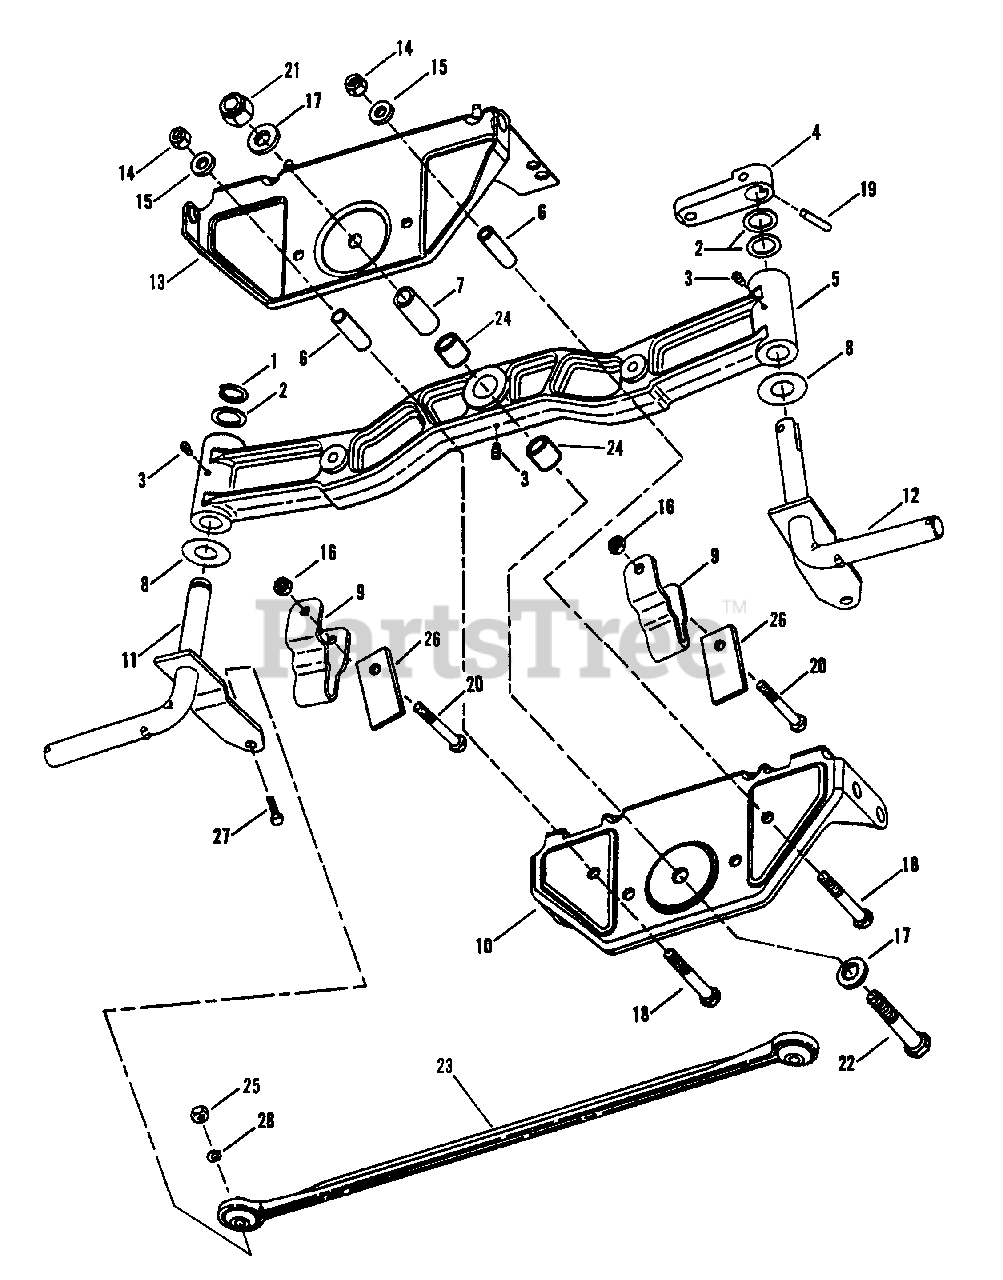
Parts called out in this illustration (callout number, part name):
1	RING, 5/8 External Retaining
2	WASHER, 49/64 x 1-1/8 x 1/16" Flat
3	FITTING, 3/16 Lube
4	ARM, Steering
5	AXLE, Cast
6	SPACER, 25/64 x 1/2 x 1-13/16"
7	SPACER, Center
8	WASHER, Thrust
9	BRACKET, Deck Hanger
10	BRACKET, Cast Axle (Rear)
11	WELDMENT, Right Hand Spindle Wheel (Long)
12	WELDMENT, Left Hand Spindle Wheel (Long)
13	ASSEMBLY, Cast Axle Front Bracket
14	NUT, 3/8-16 Hex Nyloc
15	WASHER, 3/8 x 5/64" Flat
16	NUT, 5/16-18 Hex Center Lock
17	WASHER, 1/2 x 3/32" Flat
18	SCREW, 3/8-16 x 2-3/4" Hex Head Cap, Grade 2
19	PIN, 1/4 x 1-1/4" Roll
20	SCREW, 5/16-18 x 2-3/4" Hex Head Cap, Grade 5
21	NUT, 1/2-13 Hex Nyloc
22	SCREW, 1/2-13 x 3" Hex Head Cap Grade 5
23	TIE ROD, Reduced Radius
24	BEARING, Sleeve
25	NUT, 3/8-16 Hex, Grade 5
26	SPACER, Steering Stop
27	SCREW, 3/8-16 x 1-1/2" Hex Head Cap, Grade 5
28	WASHER, 3/8 Split Lock
